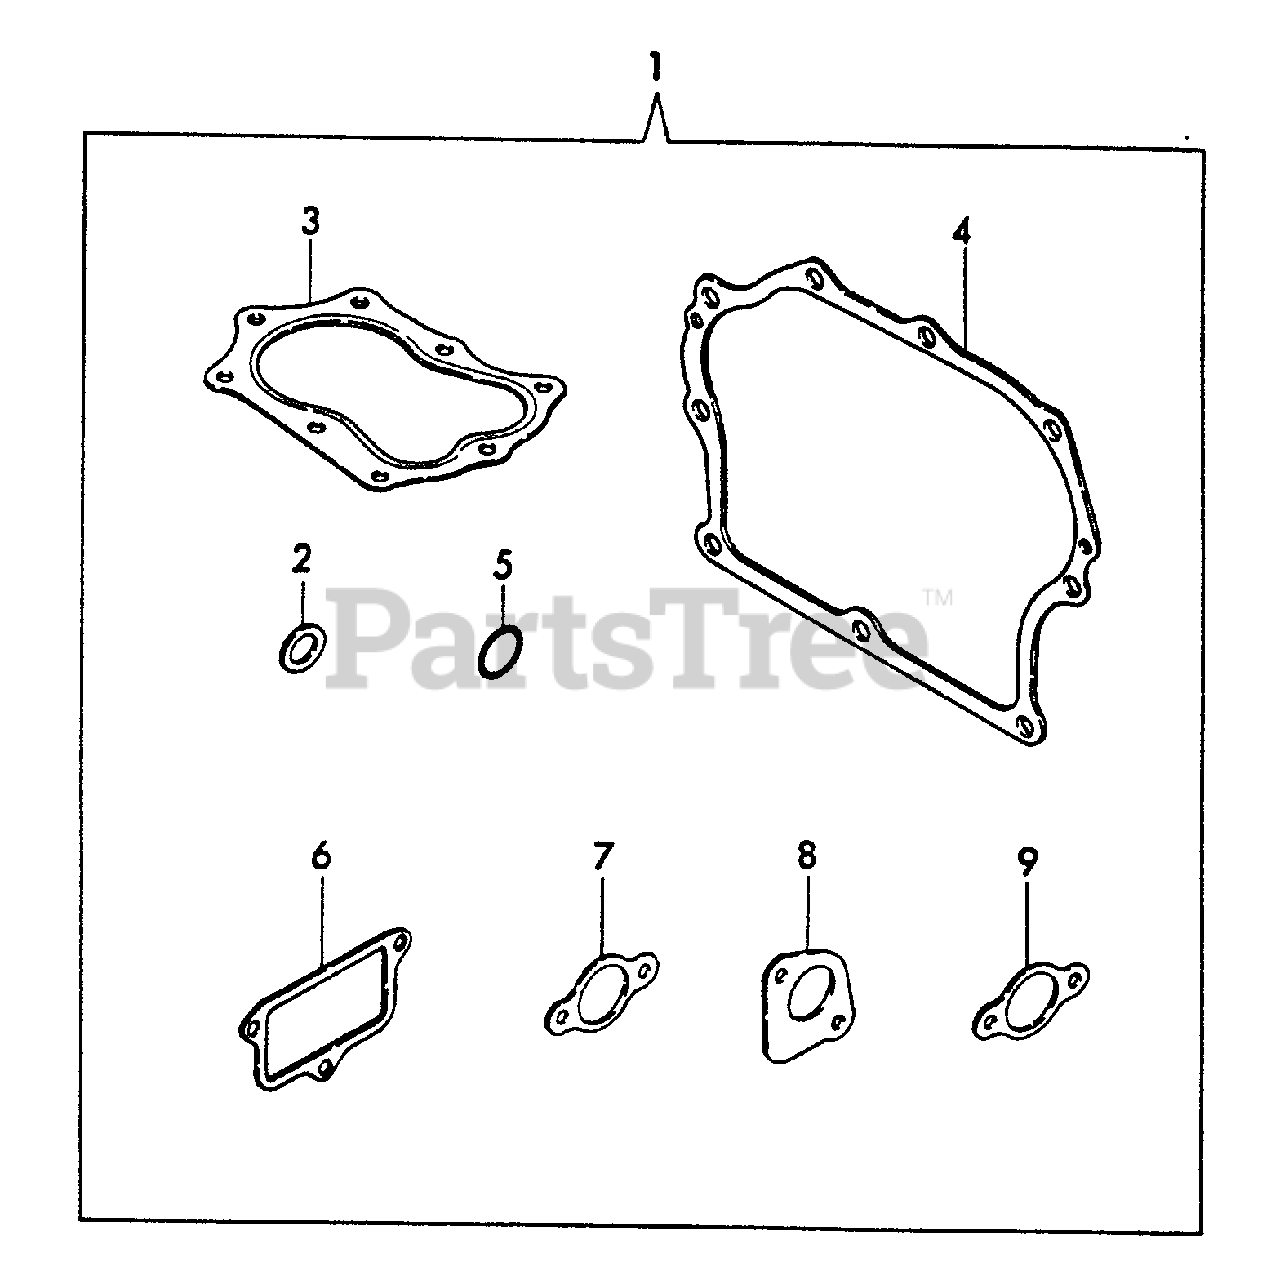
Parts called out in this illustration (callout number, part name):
1	GASKET KIT
2	GASKET
3	GASKET, CYLINDER
4	GASKET, CRANKCASE
5	O-RING - 18
6	GASKET, BREATHER
7	GASKET, INTAKE
8	GASKET, EXHAUST
9	GASKET, INTAKE
